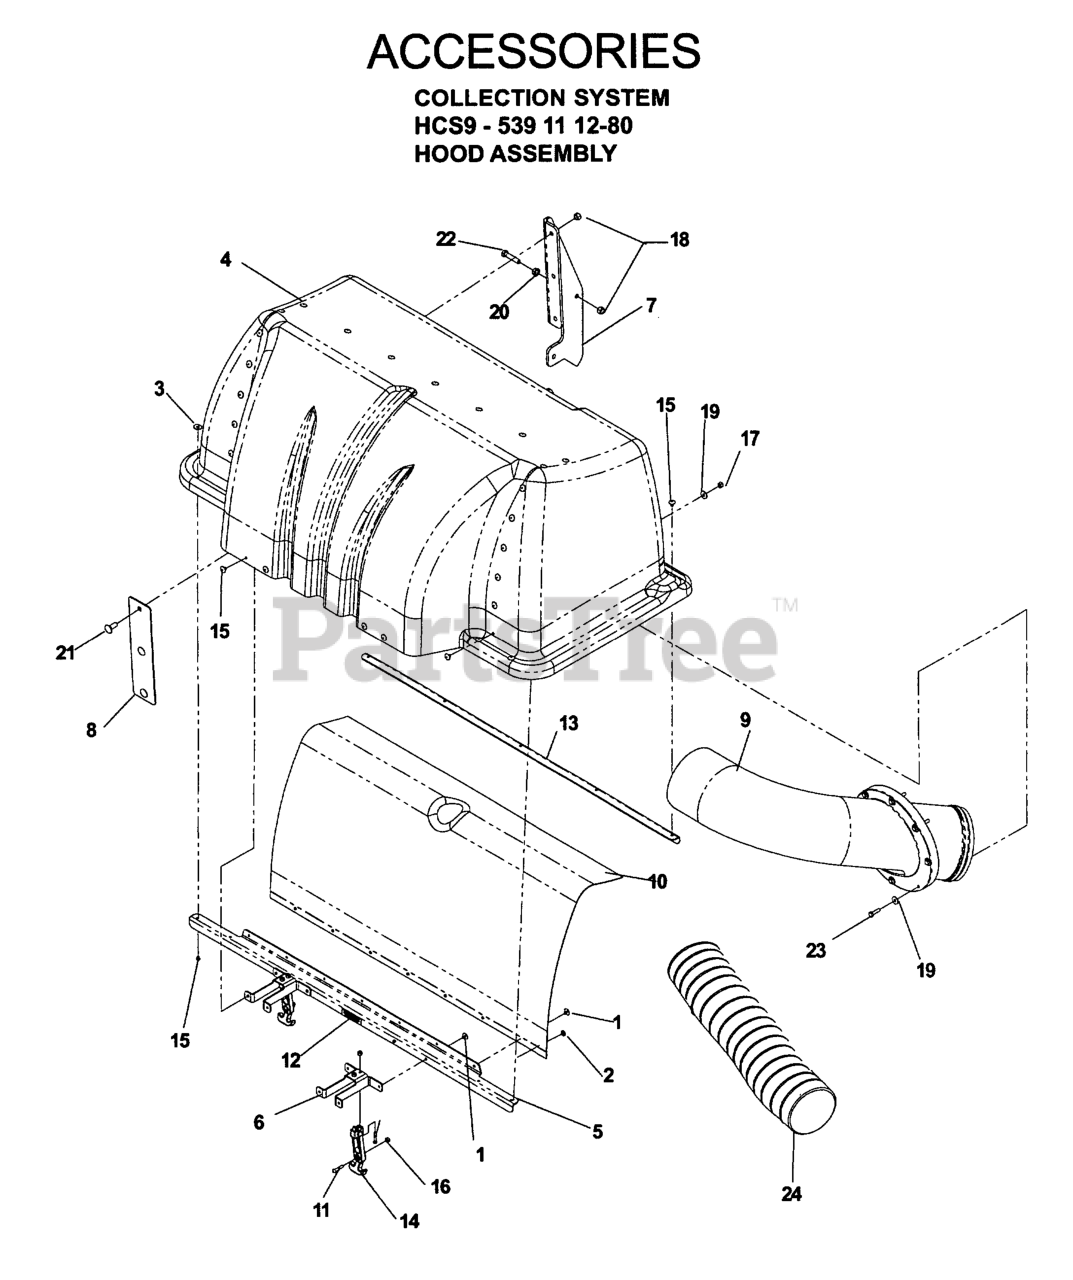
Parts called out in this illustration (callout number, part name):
1	RIVET E/16 X 1/4 LG FLG
2	WASHER #10
3	WASHER, #10 MACH SCR BLK OX
5	HOOD SUPPORT
6	SUPPORT, DRAW LATCH
7	HOOD HINGE
8	MOUNT PLATE
10	MESH, POLY DIAMOND
11	SCR, #10-24 X 1-1/8
12	DECAL, VENTILATION
13	HOOD SUPPORT, REAR
14	DRAW LATCH, FLEXIBLE T-HANDLE
15	RIVERT, 3/16, STAVEX
16	NUT 10-24 NYLOC
17	NUT.1/4-20.HEX.NYLOC.ZD
18	NUT 3/8-16 NYLOC
19	WASHER 1/4 FLAT
20	NUT 3/8C WHIZ
21	RHSNB 3/8C X 1
22	HCS 3/8-16 X 1 3/4 GR5
23	BOLT 1/4C X 1 3/4
24	HOSE 7 X 54 CLEAR
